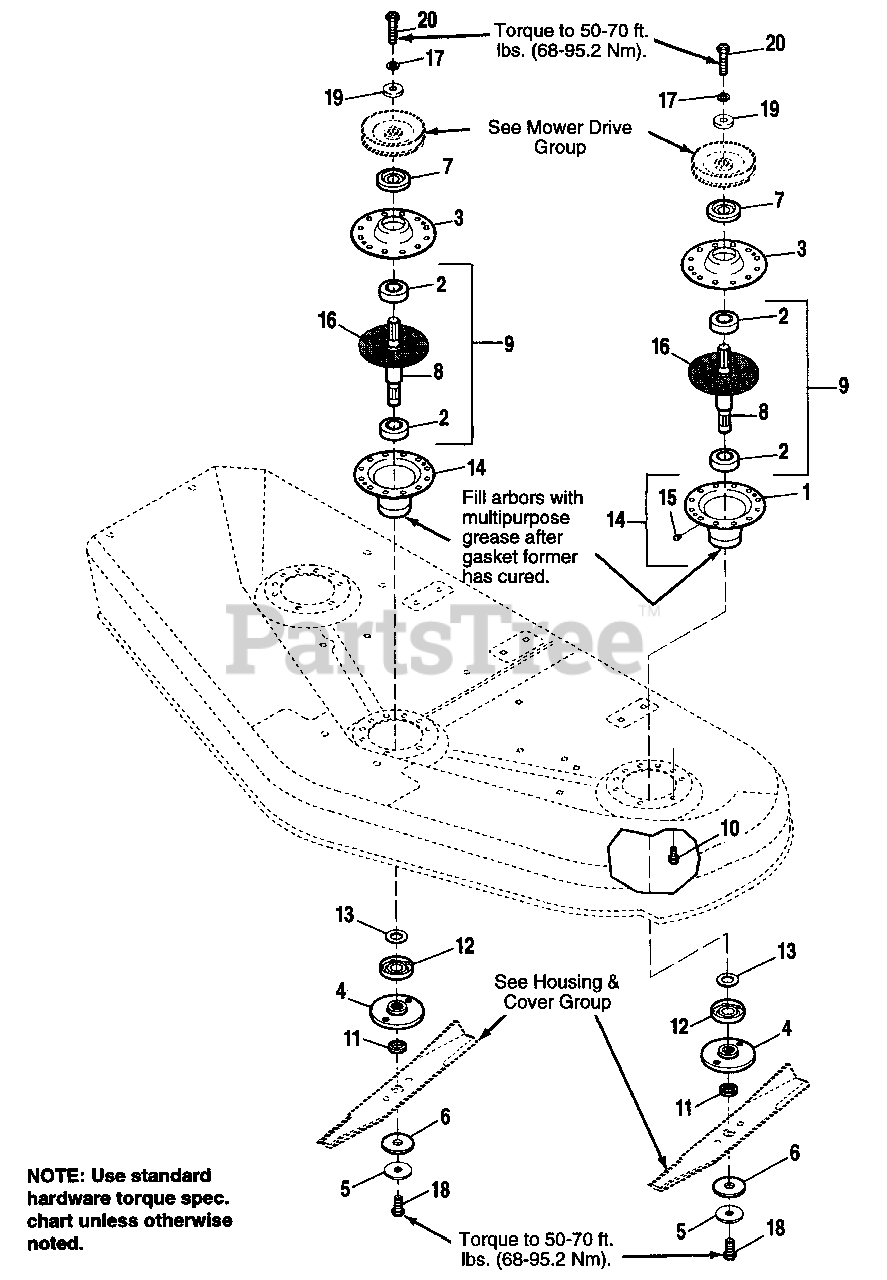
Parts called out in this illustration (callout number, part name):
2	BEARING ASSY.
3	HOUSING, Top
4	ADAPTOR, Blade
5	WASHER, Spring
6	WASHER, Spine
7	SHIELD, Bearing, Upper
8	SHAFT, Arbor
9	SHAFT & BEARING ASSY. (Incl. Ref. Nos. 2 & 8)
10	SCREW, Taptite, 5/16-18 x 3/4
11	COLLAR, Mower Arbor
12	SHIELD, Grass
13	WASHER, Shim
14	HOUSING ASSY., Arbor Bottom (Incl. Ref. Nos. 1-15)
15	FITTING, Grease
16	GASKET, Foam
17	LOCKWASHER, 7/16
18	CAPSCREW, Hex, 7/16-14 x 1
19	WASHER, 7/16
20	CAPSCREW, Hex, 7/16-14 x 1-3/4
